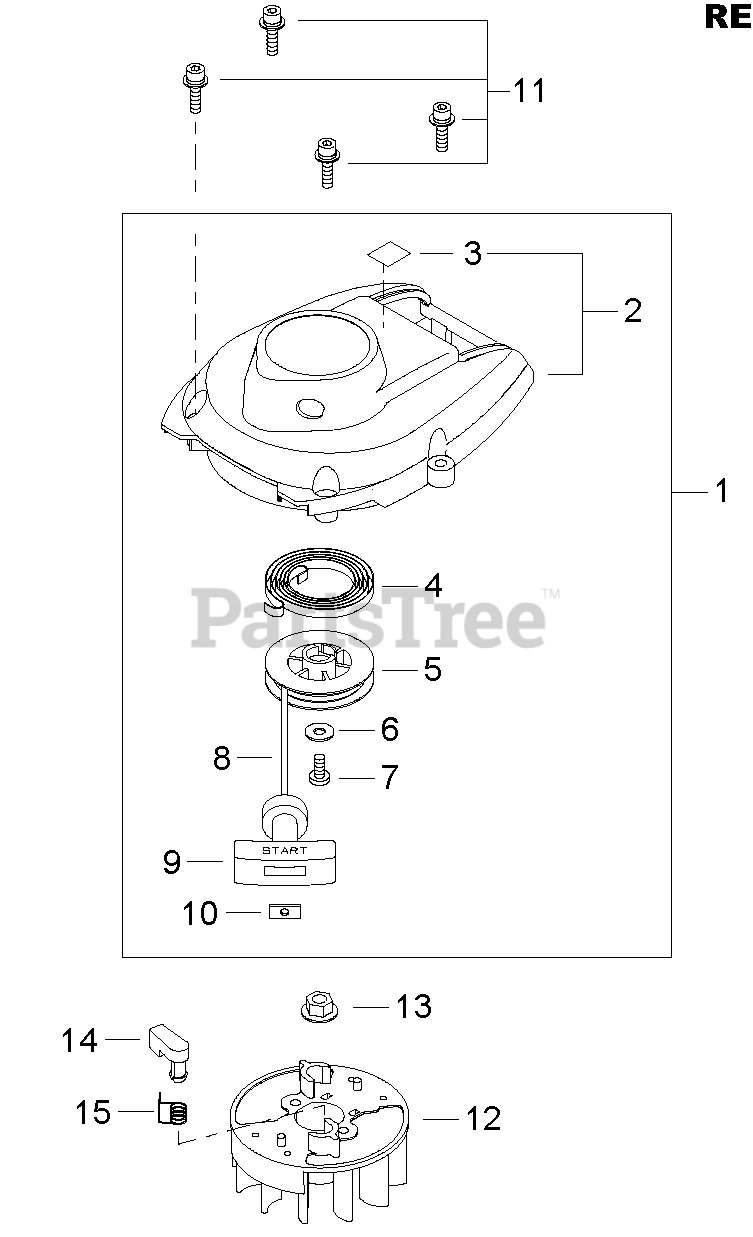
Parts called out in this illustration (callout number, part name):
1	STARTER ASSY
2	STARTER ASSY
3	LABEL - HOT SURFACE
4	SPRING, REWIND
5	REEL, ROPE
6	WASHER - 5
7	SCREW - 5
8	ROPE, STARTER
9	GRIP, STARTER
10	RETAINER, ROPE
11	SCREW - 5X20
12	FLYWHEEL
13	NUT - 8
14	PAWL, STARTER
